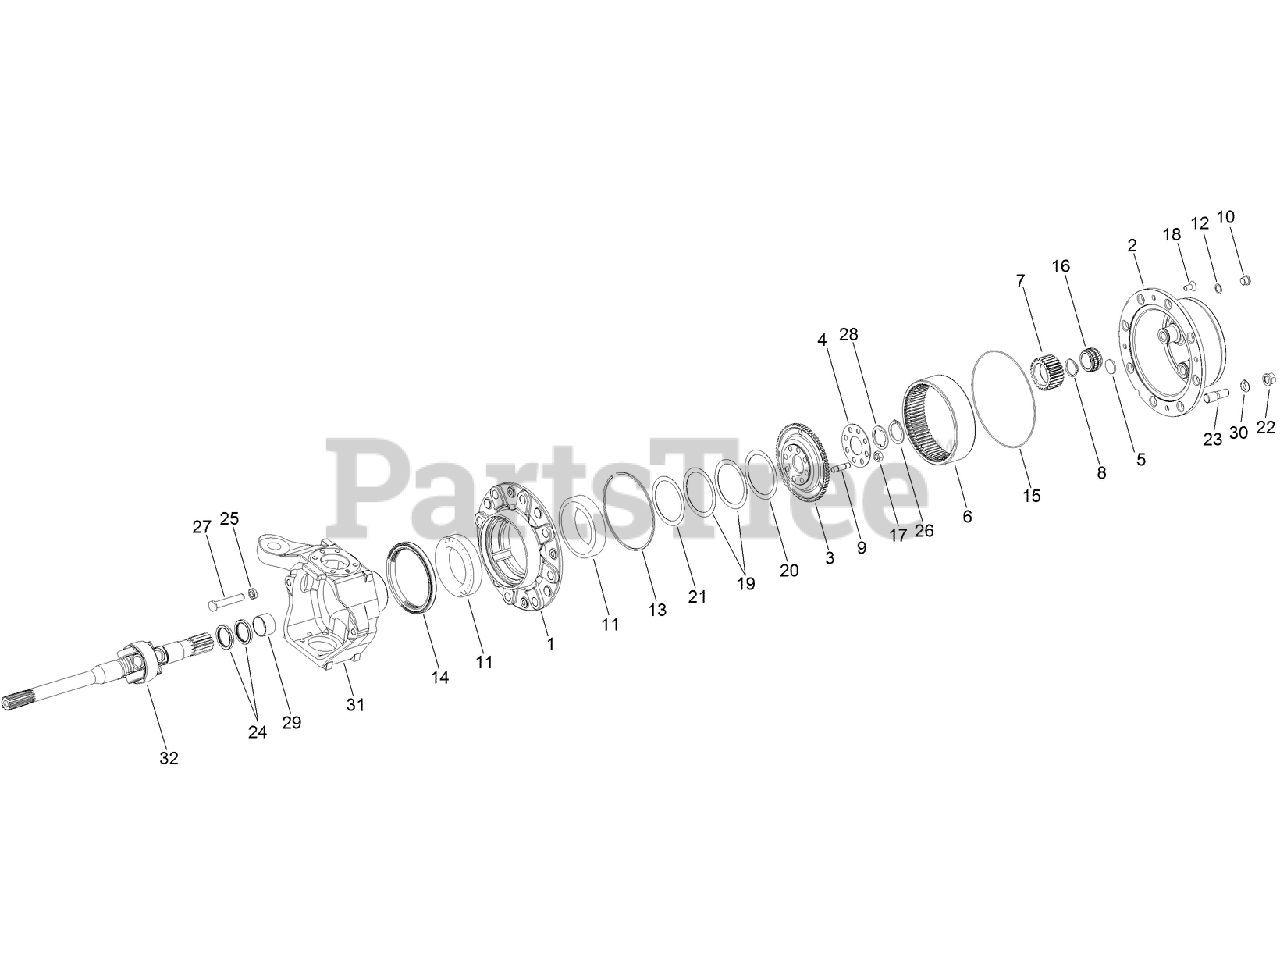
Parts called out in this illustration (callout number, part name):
1	HUB-WHEEL
2	HUB-PLANETARY
3	FLANGE-CROWN
4	RING-CROWN
5	SHIM-CROWN, WHEEL
6	WHEEL-CROWN
7	GEAR-PLANETARY
8	RING-SNAP
9	BOLT-STUD
11	BEARING
12	WASHER-COPPER
13	RING-RETAINING
14	SEAL-OIL
15	O-RING
16	BEARING-ROLLER
19	SHIM (0.2)
20	SHIM (0.1)
21	SHIM (0.35)
23	BOLT-STUD
24	SEAL-OIL
26	RING-SNAP
27	SCREW-END, STEERING
28	SHIM-CROWN
29	BUSHING
30	WASHER-ELASTIC
31	JOINT-LH, ARTICULATED
32	SHAFT-DRIVE
